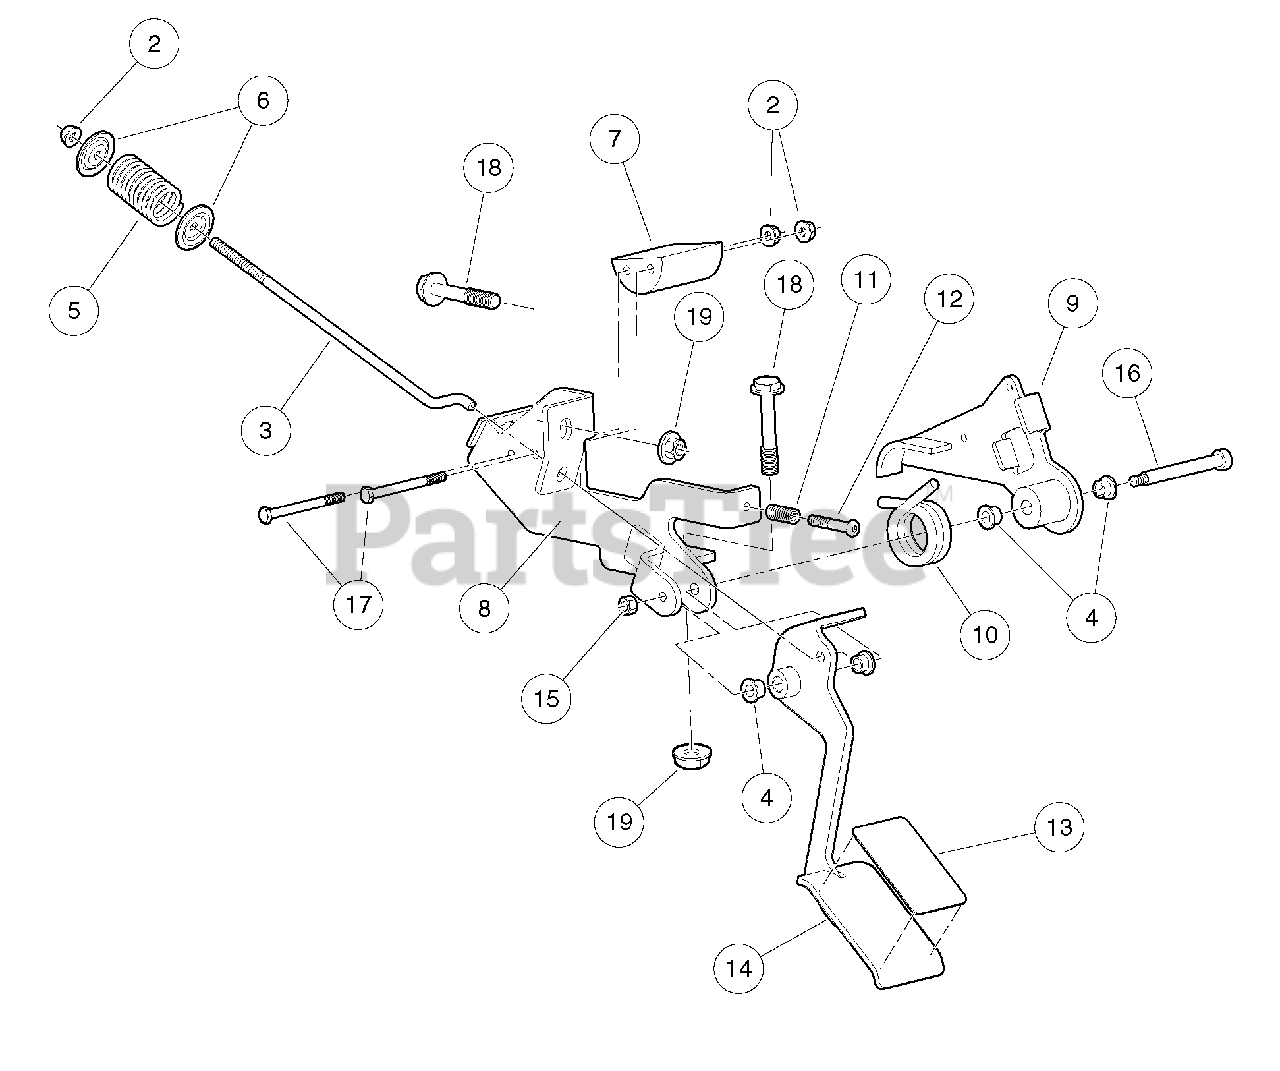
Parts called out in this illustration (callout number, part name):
1	Asm, Pedal, Accelerator
2	Nut-m6x1.0 Flng All Mtl Lock
3	Pullrod, Spring, Compression
4	Bushing, Greaseless
5	Spring, Comp, Pedal, Pullrod
6	Washer, Retaining Spring, 7mm
7	Guide, Cable, Accelerator
8	Weldment, Bracket, Pedal
9	Weldment, Lever, Motion, Lost
10	Spring, Torsion
11	Spring, Stop, Pedal
12	Bolt, Stop, Pedal
13	Pad, Grip Tape, Accelerator
14	Weldment, Pedal, Accelerator
15	Nut M6x1 Mech Def Center
16	Bolt, Shoulder, M8 X 70, Hc
17	Bolt, M6 X 1 X 70
18	Bolt Flanged Head, M8 X 1.25 X 65
19	Lock Nut, Flg M8 X 1.25 Nylon
